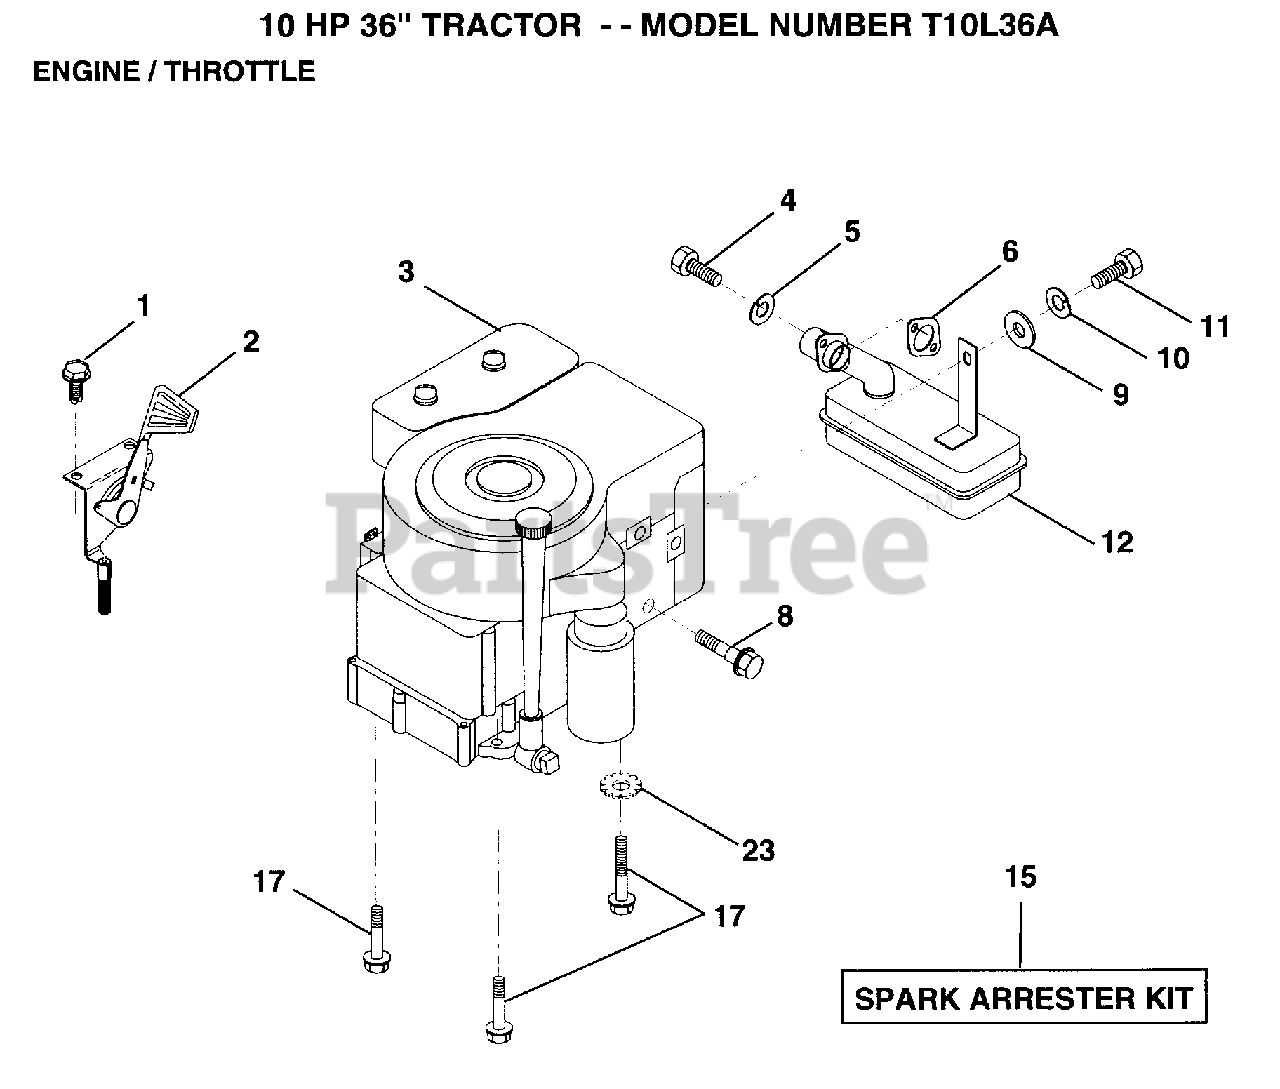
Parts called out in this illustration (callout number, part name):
1	SCREW.1/4-20X1/2
2	"CONTROL,THROTTLE"
3	ENGINE, B&S 10HP
4	SCREW
5	LOCKWASHER
8	BOLT T
10	LOCKWASHER
12	MUFFLER
17	SCREW LT
23	LOCKWASHER
